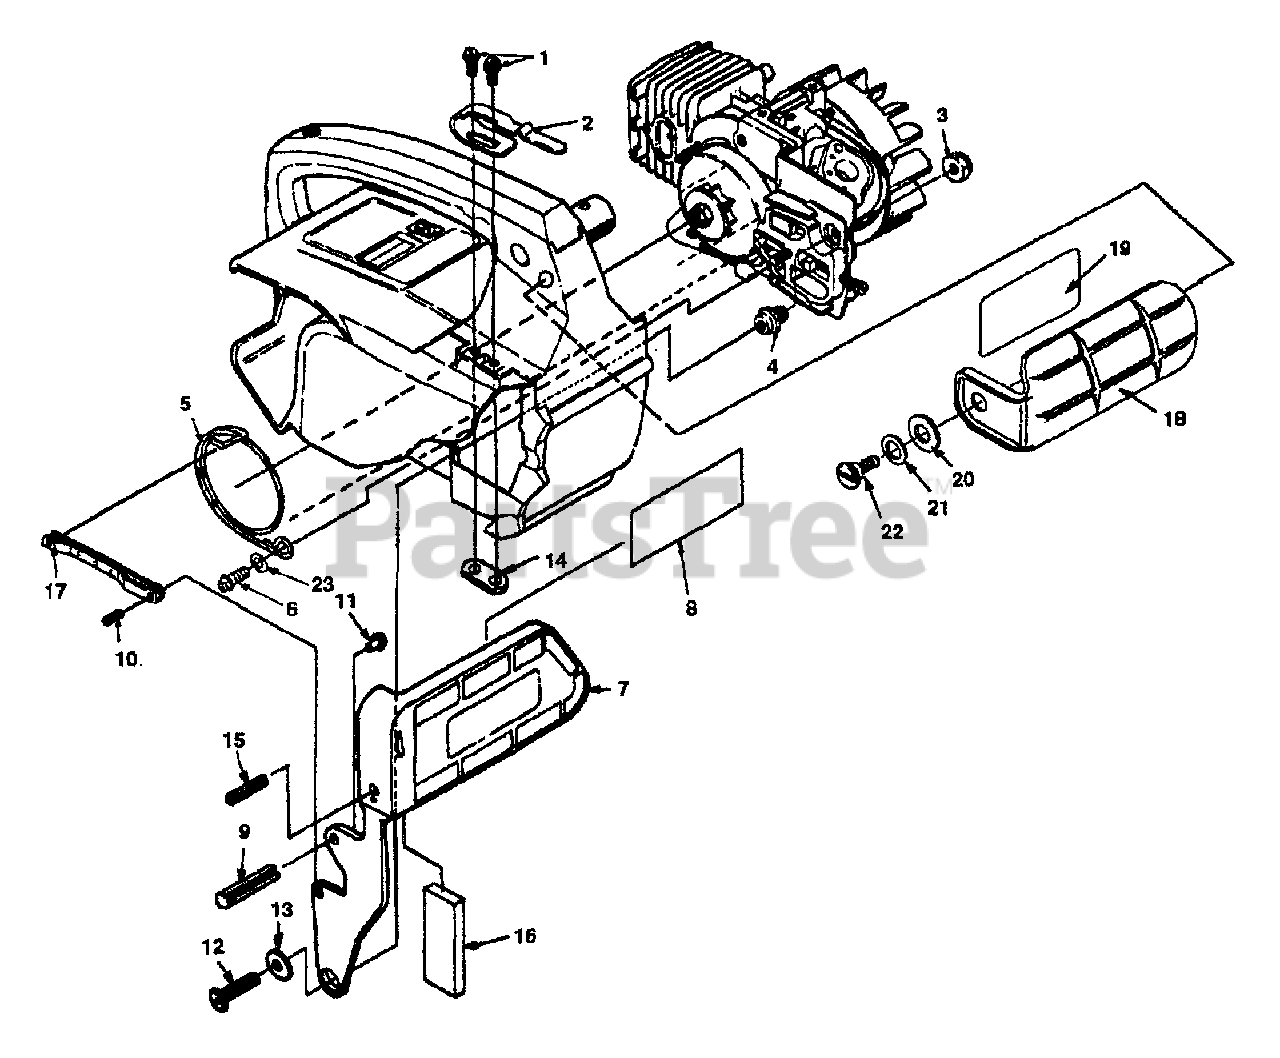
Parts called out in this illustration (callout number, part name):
1	SCREW-Hex Hd. w/Washer (8-32 X 1/2")
2	CLIP-Retaining
3	NUT-Hex, Jam
4	POST-Chain Brake
5	BAND-Brake
6	SCREW-Thread Form (10-24 x 3/4")
7	HANDGUARD & LEVER
8	DECAL-Safety
9	PIN-Roll (3/16 X 1")
10	PIN-Roll
11	SCREW-Drive
12	SCREW-Machine, Pan Hd. (10-32 X 1/2")
13	WASHER-Flat
14	NUT-Weld
16	WEIGHT-Handle
17	PIVOT-Link
18	HANDGUARD KIT
19	DECAL-Handguard
20	WASHER-Curve Spring
21	WASHER-Flat
22	SCREW-Shoulder
23	WASHER- Flat (#10)
